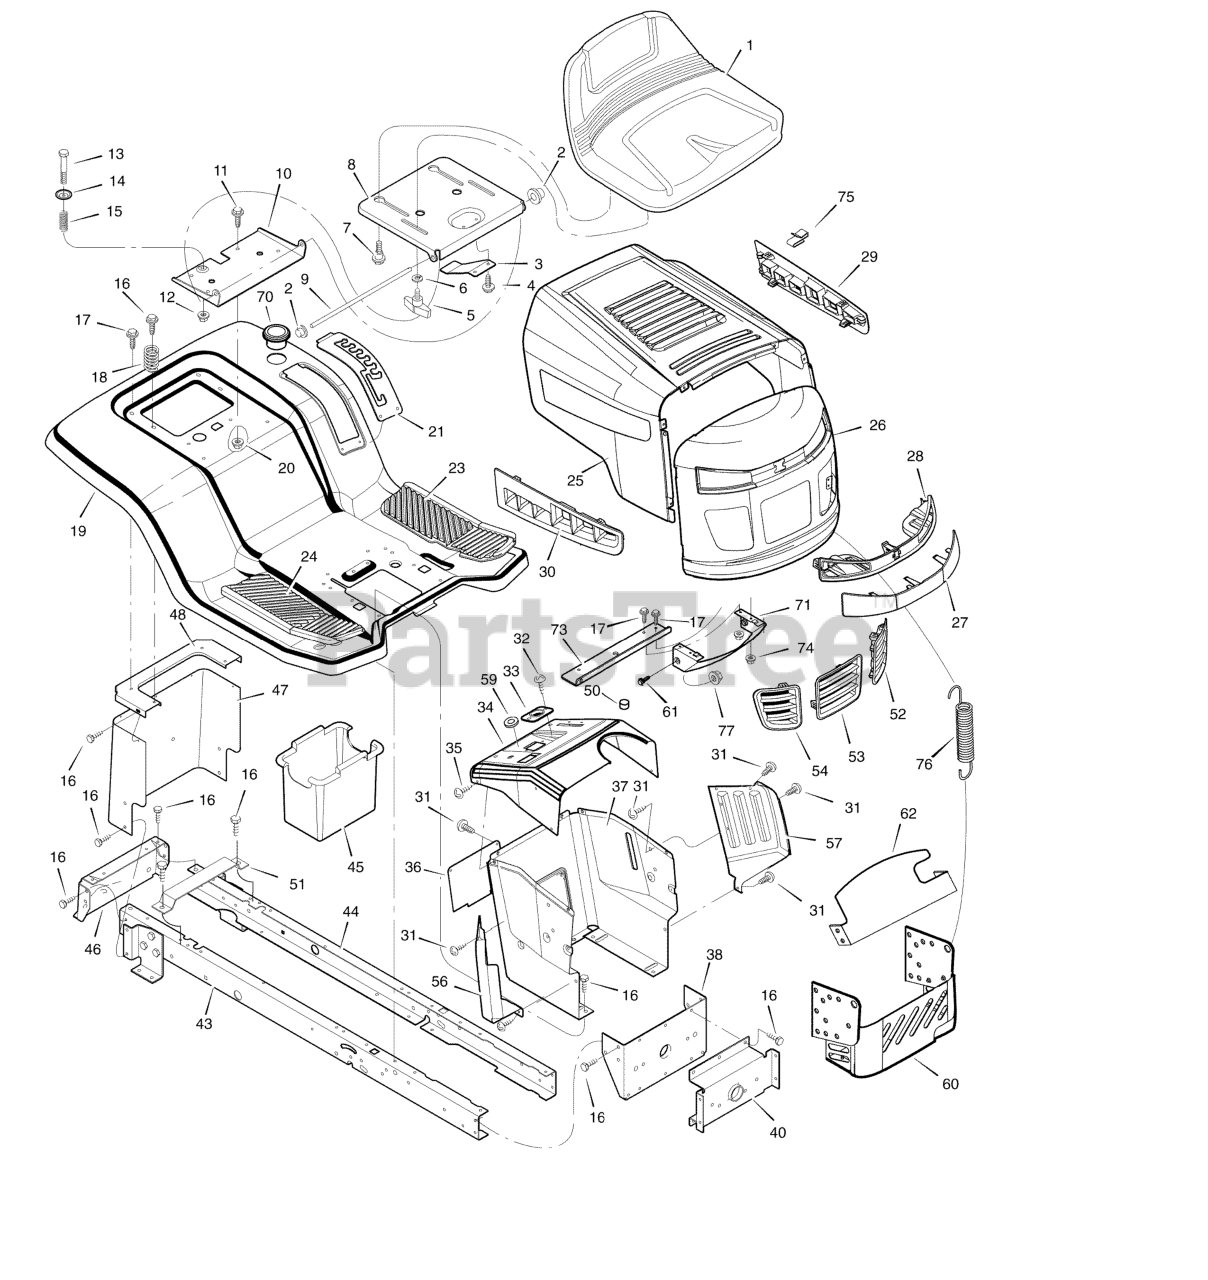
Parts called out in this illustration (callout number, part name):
1	Seat
2	Cap, Push On
5	Bolt, Wing
6	Washer
7	Bolt, Shoulder
8	Support, Seat
9	Rod, Pivot
10	Bracket, Pivot
11	Bolt
13	Bolt, Shoulder
14	Washer, Cup
19	Deck, Seat
20	Nut
21	Plate, Index
23	Mat, Left
24	Mat, Right
25	Hood
26	Grille
27	Plastic Cover, Center
28	Headlamp Housing, Center
29	Hood Insert, Left
30	Hood Insert, Right
33	Bearing, Steering
36	Panel, Access
37	Support, Dash
38	Bracket, Rear Hanger
40	Axle, Hanger
43	Frame, Right
44	Frame, Left
45	Container, Battery
46	Plate, Hitch
47	Plate, Rear
48	Top, Rear Plate
50	Bumper, Black
51	Bracket, Battery Support
52	Grille Insert, Left
53	Grille Insert, Center
54	Grille Insert, Right
56	Panel, Side, RH
57	Panel, Side, LH
59	Grommet, Parking Brake
60	Shield, Heat
61	Bolt, Shoulder
62	Guard, Heat Shield Upper
70	Holder, Cup
71	Bracket, Lower Pivot
73	Bracket, Grille Support
74	Nut, Flange Lock
75	Retainer, S-Clips
76	Spring, Extension
77	Nut
